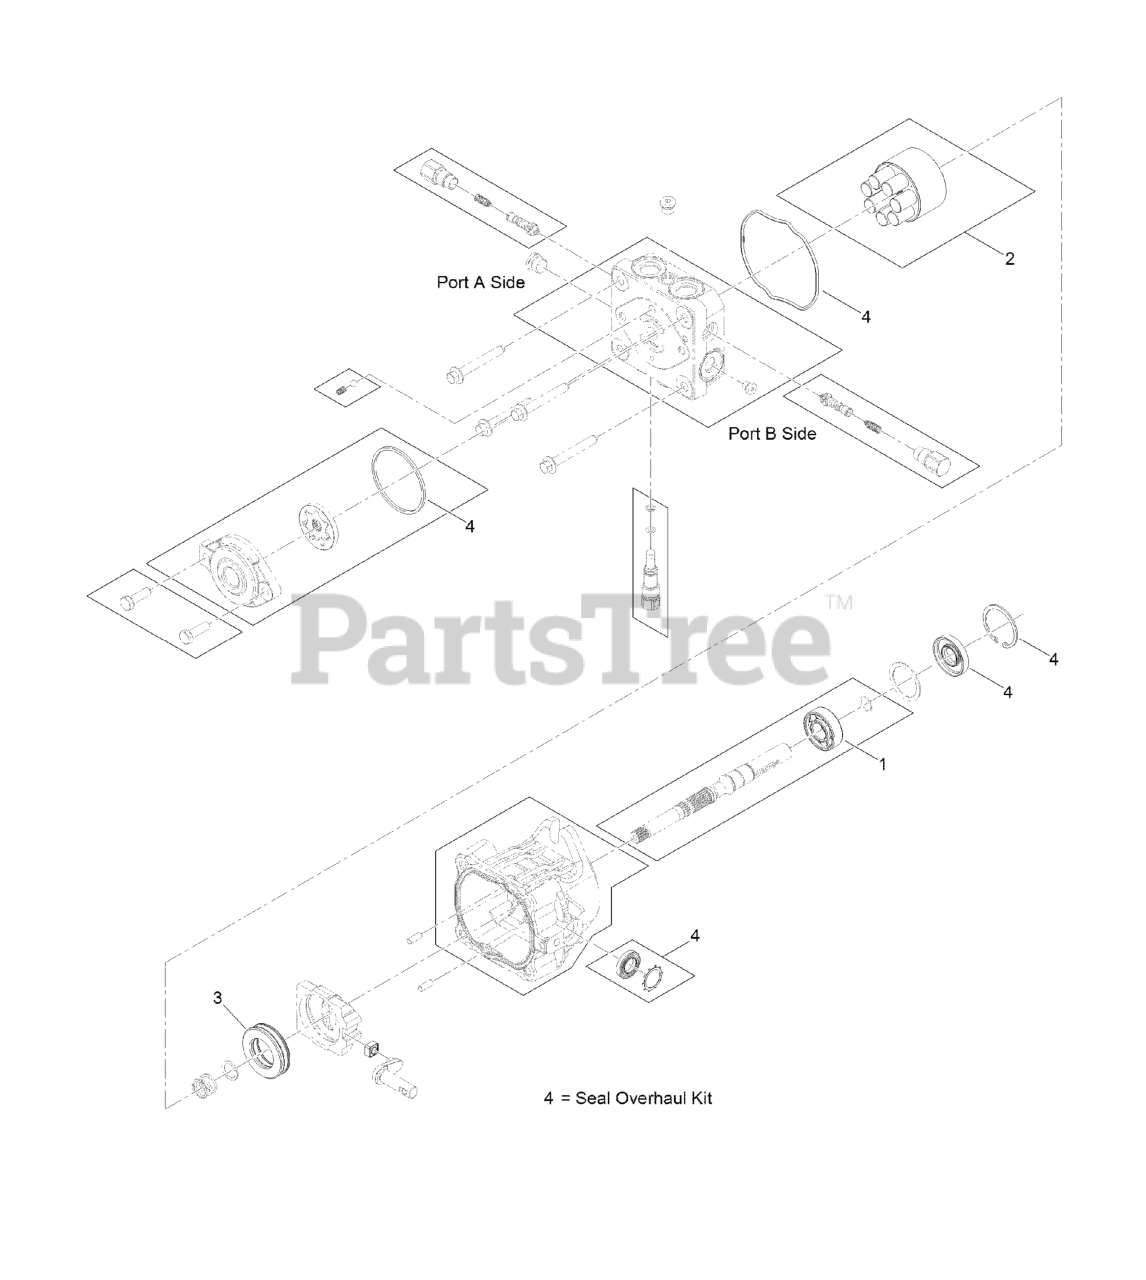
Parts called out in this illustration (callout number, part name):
1	BEARING-BALL
2	CYLINDER BLOCK KIT
3	BEARING-THRUST, PLASTIC C
4	SEAL OVERHAUL KIT
